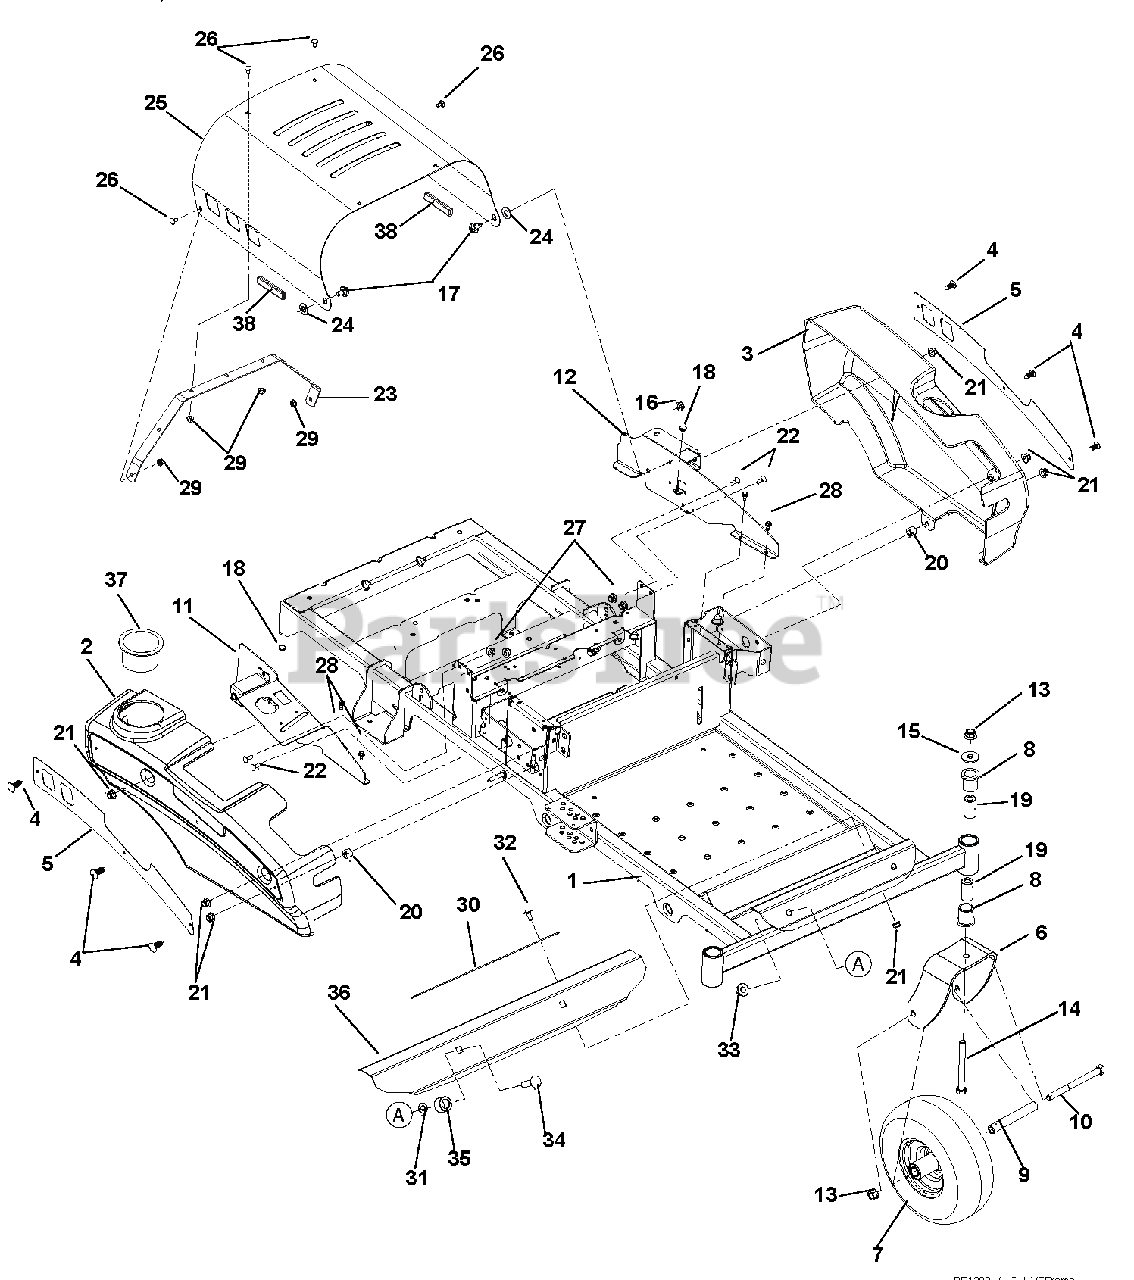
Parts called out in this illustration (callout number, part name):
1	WMT, FRAME ZOOM/ZT
2	FENDER, RH
3	FENDER, LH
4	RIVET, .25 NYLON PANEL
5	PLATE, FENDER
6	WMT, CASTER FORK
7	TIRE/WHL ASM, FRONT
8	BSHG-FLG 1.00X1.25X1.50X1.50
9	SPACER, ROLLED WHEEL
10	@BLT-HEX .50-13X6.50 GR5 YWZC
11	WMT-RH FENDER MOUNT
12	WLDMNT, LH FENDER MOUNT
13	@NUT-LK-TOP-FLG .50-13 YWZC
14	@BLT-HEX .50-13X5.00 GR5 YWZC
15	WSHR-FL-STL.511X1.441X.125 YWZ
16	@NUT-LK-TOP-FLG .38-16 YWZC
17	BOLT-SHLDR .375-16X.150
18	BUMPER GROMMET
19	SPACER, CASTER .50X1.00X1.84
20	BSHG-SLV .391X.688X.52 PM
21	@NUT-LK-NYL-FLG .31-18 YWZC
22	@BLT-RDHDSQNK .25-20X.75 G5YZ
23	BRACE, HOOD
24	WSHR-FL-NYL .518X1.000X.080
25	HOOD, ZOOM/ZT
26	@BLT-RDHDSQNK .25-20X.50 G5YZ
27	@NUT-LK-NYL-FLG .25-20 YWZC
28	@SCR-TAP .25-20X.50 HWH TR YWZ
29	@NUT-LK-TOP-FLG .25-20 YWZC
30	GRIP, ADHESIVE (1" X 16" BLK)
31	NUT-PUSH, .50
32	@BLT-RDHDSQNK .31-18X.75 G5YZ
33	@NUT-LK-NYL-FLG .50-13 YWZC
34	@BLT-RDHDSQNK .50-13X1.75 G5YZ
35	TUBE, UPPER CONTROL PIVOT
36	FOOTREST
37	CUPHOLDER, SNAP-IN 3.75OD
38	EDGING, CLUTCH PADDLE - 2.00"
